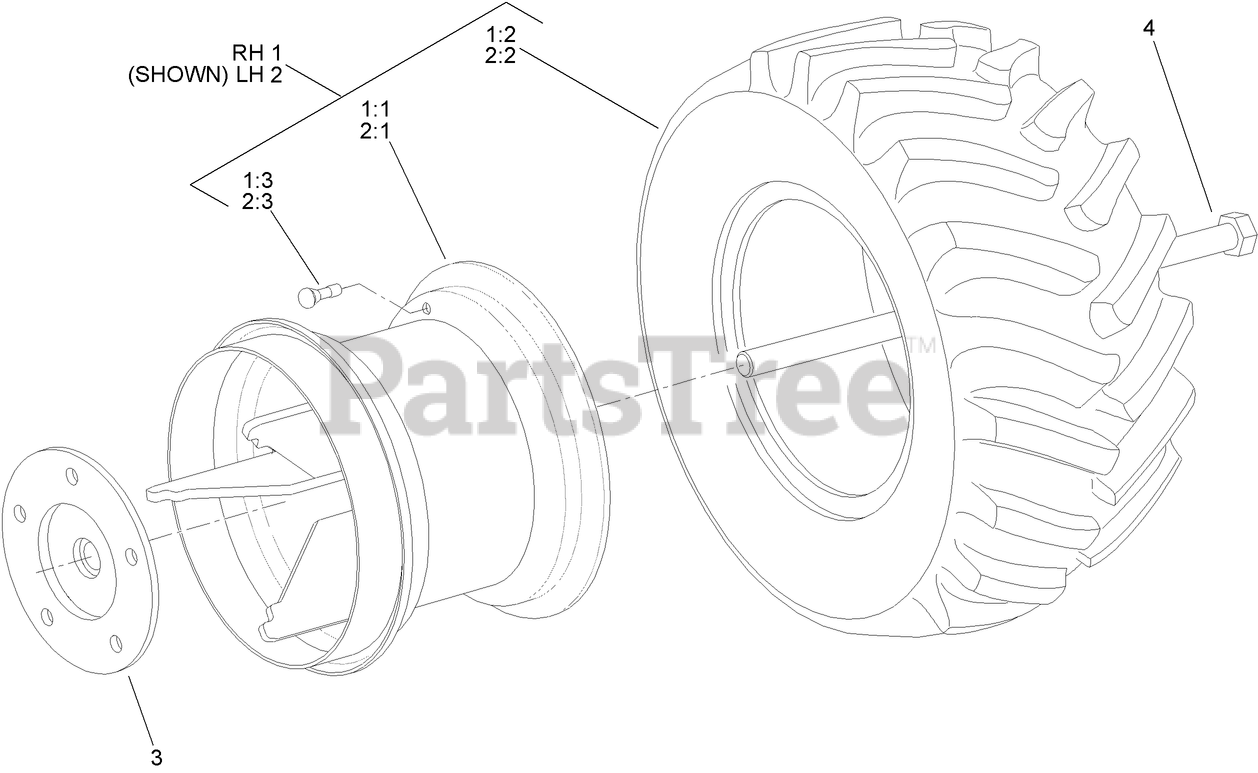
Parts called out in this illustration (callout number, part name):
1	RH DUAL 26 INCH WHEEL ASM
1:1	WHEEL-DUAL
1:3	STEM-VALVE
2	LH DUAL 26 INCH WHEEL ASM
2:1	WHEEL-DUAL
2:3	STEM-VALVE
3	PLATE-RETAINER
4	SCREW-HH
